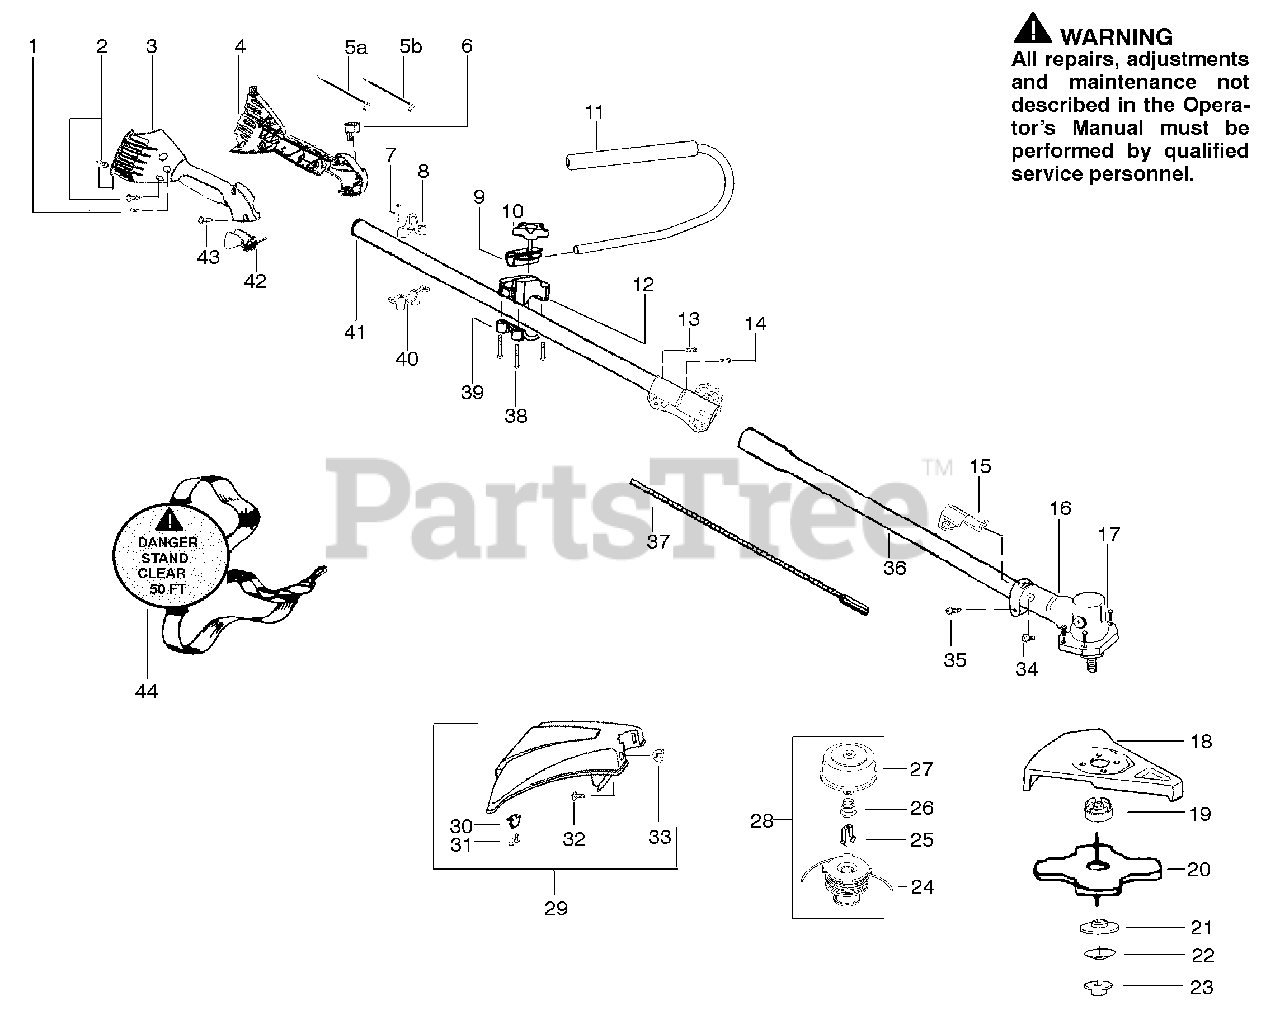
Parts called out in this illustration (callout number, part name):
1	Screw-alignment
3	Throttle hsg-right
4	Kit-Left throttle hsg
5A	Wire Assy-Front Wire
5B	Wire Assy-Front Wire (Upper)
6	Kit-Switch
8	Clamp-Harness (upper)
9	Clamp-Handlebar
10	Knob
11	Assy.-Handlebar
12	Base-Clamp
13	Screw-Align
15	Bracket-Shield
16	Kit-Gearbox
18	Kit-Metal Shield
19	Dust cup
20	Accy.-Weed Blade
22	Washer-Belleville
23	Nut-Flange
24	Accy-Wound Spool
25	Retainer-Spool
26	Spring-Return
27	Assy-Hub/Arbor
28	Assy-Cutting Head
29	Kit-Shield Assy.
30	Limiter-Line
31	Screw
33	Wingnut
36	Assy-Lower Shaft
37	Shaft-Flex (lower)
39	Clamp-Tube
40	Clamp-Harness (lower)
41	Kit-Upper Shaft
42	Lever-Throttle
44	Shoulder Strap
